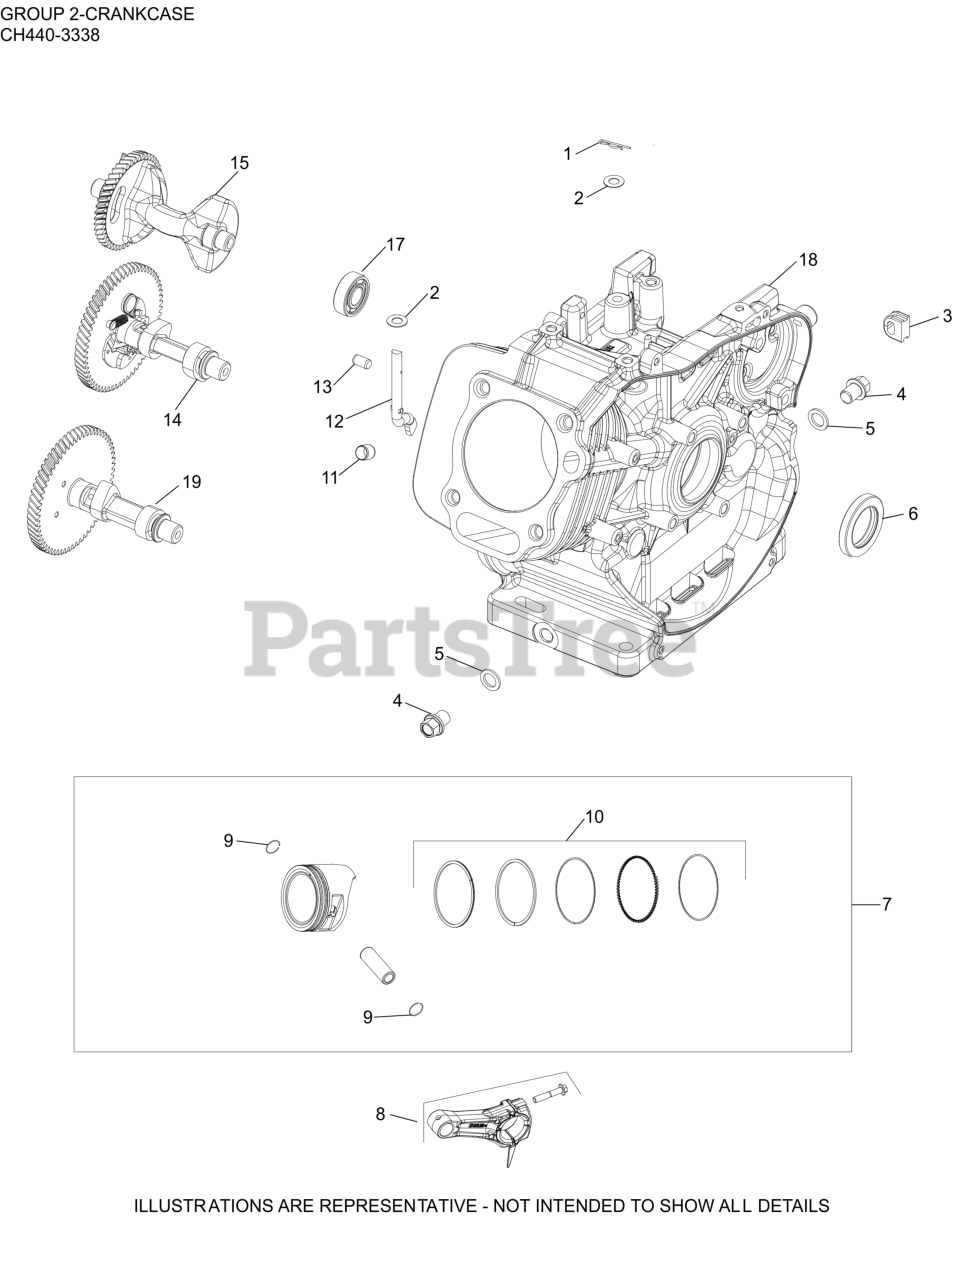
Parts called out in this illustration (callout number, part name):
1	CLIP, GOVERNOR SHAFT
2	WASHER, FLAT
3	GROMMET, CRANKCASE
4	KIT, DRAIN PLUG
5	WASHER, DRAIN PLUG
6	SEAL, CRANKSHAFT
7	KIT, PISTON W/RING SET (STD)
7	KIT, PISTON (0.25 O.S.)
8	ROD, CONNECTING ASSEMBLY
9	RETAINER, PISTON
11	PIN, DOWEL CYLINDER HEAD
12	SHAFT, GOVERNOR CROSS
13	PIN, DOWEL
14	CAMSHAFT ASSEMBLY
15	SHAFT, BALANCE
17	BEARING, BALANCE SHAFT
18	CRANKCASE
19	CAMSHAFT, NO ACR
